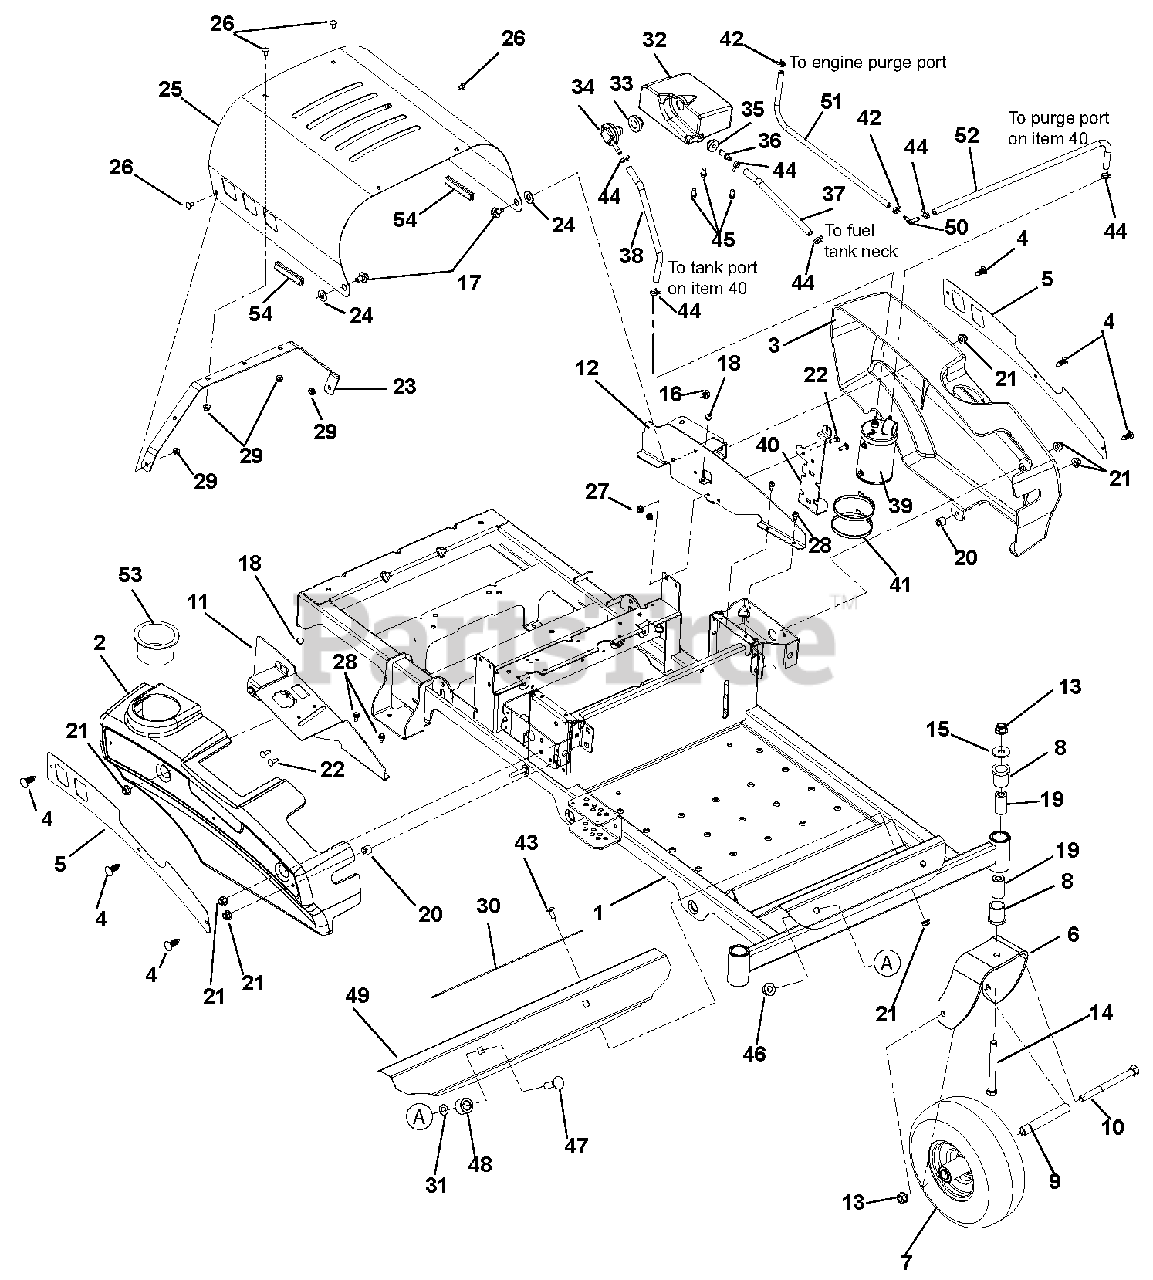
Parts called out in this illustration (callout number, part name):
1	Weldment, Frame
2	Fender, Right Hand
3	Fender, Left Hand
4	Rivet, Nylon
5	Plate, Fender
6	Fork, Caster
7	Wheel/Tire Assembly, 11.0 x 4.0 x 5.0
8	Bushing, Flange 1.00 x 1.25 x 1.50 x 1.50
9	Spacer, Wheel
10	Bolt, Hex .50-13 x 6.50
11	Weldment, Fender Mount Right Hand
12	Weldment, Fender Mount Left Hand
13	Nut, Locking, Top, Flange .50-13
14	Bolt, Hex .50-13 x 5.00
15	Washer, Flat Steel .511 x 1.441 x .125
16	Nut, Locking, Top, Flange .38-16
17	Bolt, Shoulder .375-16 x .135
18	Bumper Grommet .125 x .250 Diameter
19	Spacer, Caster
20	Bushing, Sleeve .391 x .688 x .52
21	Nut, .31-18 Nyloc Flange
22	Bolt, Round Head Square Neck .25-20 x .75
23	Hood Brace
24	Washer, Flat, Nylon .52 x 1.00 x .08
25	Hood, Zoom
26	Bolt, Round Head Square Neck .25-20 x .50
27	Nut, .25-20 Nyloc Flange
28	Screw, Tapping .25-20 x .50 Hex Washer Head Thread
29	Nut, Locking Top Flange .25-20
30	Grip, Adhesive (1" x 16" BLK)
31	Nut, Push .50
32	Tank, ZT/Waw Fuel Exp.
33	Grommet, Remote Vent Nitrile
34	Vent, Roll-Over (.25"ID Hose)
35	Bushing, Flange .375 x 1.062 x .625 R
36	Fitting, Straight Fuel
37	Hose, .25 Low-Perm Bulk Gas
38	Hose, .25 Low-Perm Bulk Gas
39	Carbon Canister, 300CC
40	Bracket, Mount, Canister BBZ
41	Plastic Tie Strap Large
42	Clamp, Hose Spring .188
43	Bolt, Round Head Square Neck .31-18 x .75
44	Clamp, Fuel Line
45	Bolt, Serrated Hex Flange Washer Head .312-18 x .50
46	Nut, Locking Nylon Flange .50-13
47	Bolt, Round Head Square Neck .50-13 x 1.75
48	Tube, Upper Control Pivot
49	Foot Rest
50	Fitting, 3/16 x 1/4 90 Deg Vac
51	Hose, .188 Low Perm Bulk (915168)
52	Hose, .25 Low Perm Bulk Gas (915168)
53	Cupholder
54	Edging, Clutch Paddle-2.00"
